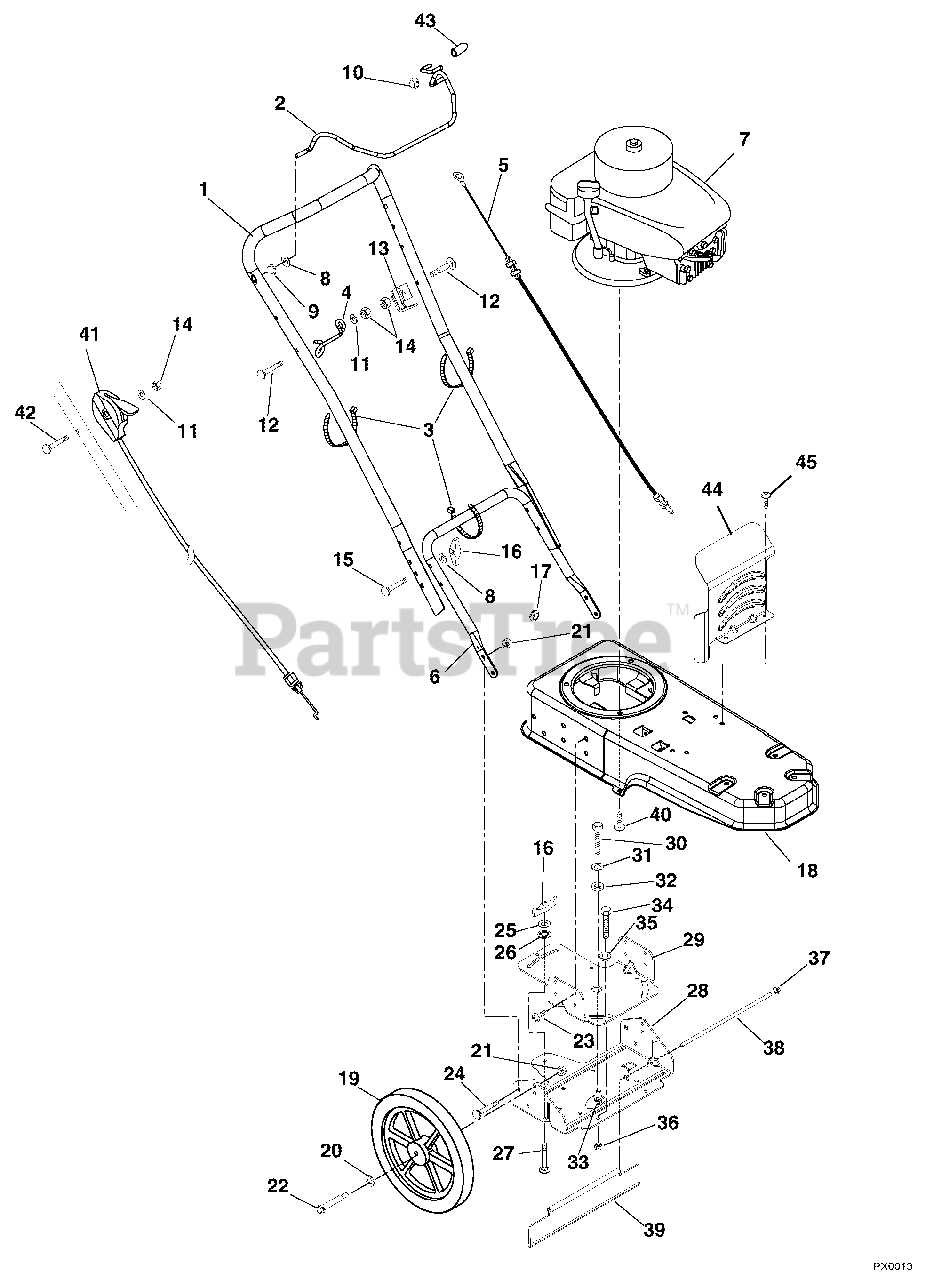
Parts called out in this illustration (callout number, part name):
1	HANDLEBAR - UPPER
2	BAIL SS LF
3	CABLE TIE LG 5-1/2
4	GUIDE - PULLCORD
5	CABLE - CONTROL
6	HANDLEBAR - LOWER
7	KIT - 6 HP TEC ENGINE-ARIENS
8	@WSHR-FL-STL.344X.688X.065YWZC
9	BSHG-FLG .325X.444X.440X.560
10	PUSH NUT, .25
11	@WSHR-FL-STL.281X.62X.065 YWZC
12	BLT-RDHDXLSQNK.25-20X1.25 G5ZC
13	ANCHOR - CABLE
14	@NUT-LK-CTR .25-20 YWZC
15	BLT-RDHDSQNKFT .31-18X2.0 G5YZ
16	KNOB - WING .312-18 UNC
17	GROMMET .50 ID
18	FRAME - TRIMMER
19	WHEEL 16 X 1.75 X .50
20	WSHR-FL-STL .52X.827X.062 YWZC
21	@NUT-LK-CTR .38-16 YWZC
22	BLT-SHLDR .38-16X2.50 HWH G5
23	@SCR-TAP .38-16X.75 HWH TR YWZ
24	@BLT-RDHDSQNK .38-16X.75 G5YZ
25	@WSHR-FL-STL.38X.875X.083 YWZC
26	NUT-PUSH .312
27	@BLT-RDHDSQNK .31-18X1.00 G5YZ
28	BRACKET - AXLE - SWIVEL
29	BASE - SWIVEL
30	@BLT-HEX .50-13X1.00 GR5 YWZC
31	@WSHR-FL-STL.563X1.38X.109YWZC
32	SPACER .531 X 1.00 X .225
33	@NUT-LK-CTR .50-13 YWZC
34	@BLT-HEX .31-18X1.00 GR5 YWZC
35	BSHG-FLG .32X.500X.344X.880
36	@NUT-LK-CTR .31-18 YWZC
37	NUT-PUSH .312 DIA. PAL
39	GUARD - REAR - SWIVEL
40	@SCR-TAP .38-16X1.00 HWH TR YZ
41	CONTROL - THROTTLE
42	BLT-RDHDXLSQNK .25-20X2.0 G5YZ
43	CAP, VINYL, .25 ID
44	GUARD - ENGINE
45	@SCR-TAP .38-16X.50 HWH TR YWZ
